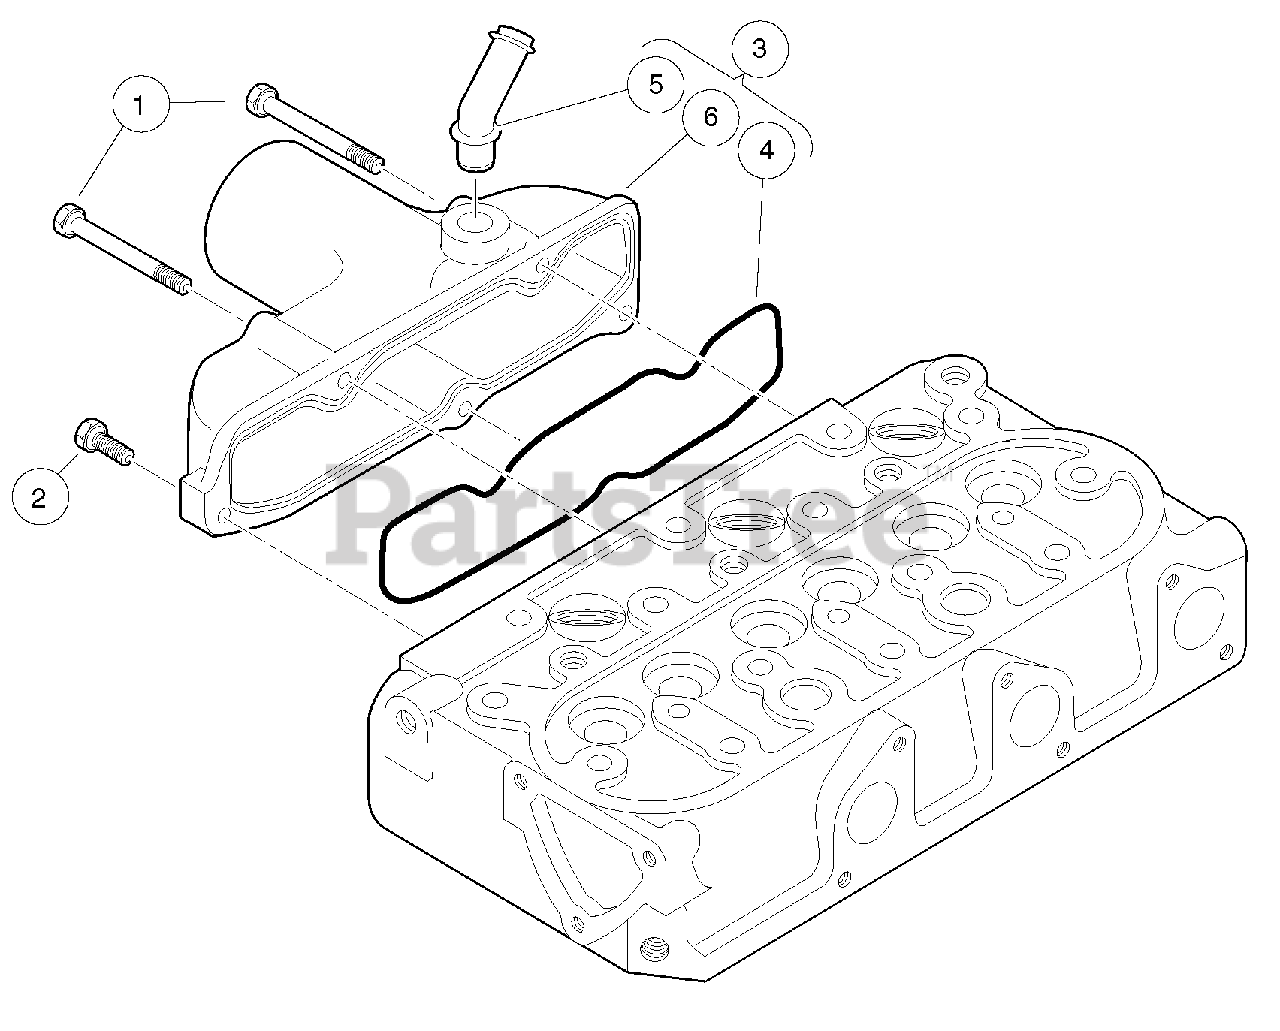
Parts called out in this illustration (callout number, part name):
1	Bolt, M6 X 1 X 45
2	Bolt, D722 Intake Manfld Lower
3	Assembly, Intake Manifold
4	Gasket, Intake Manifold
5	Pipe, Breather
6	Manifold, Intake
